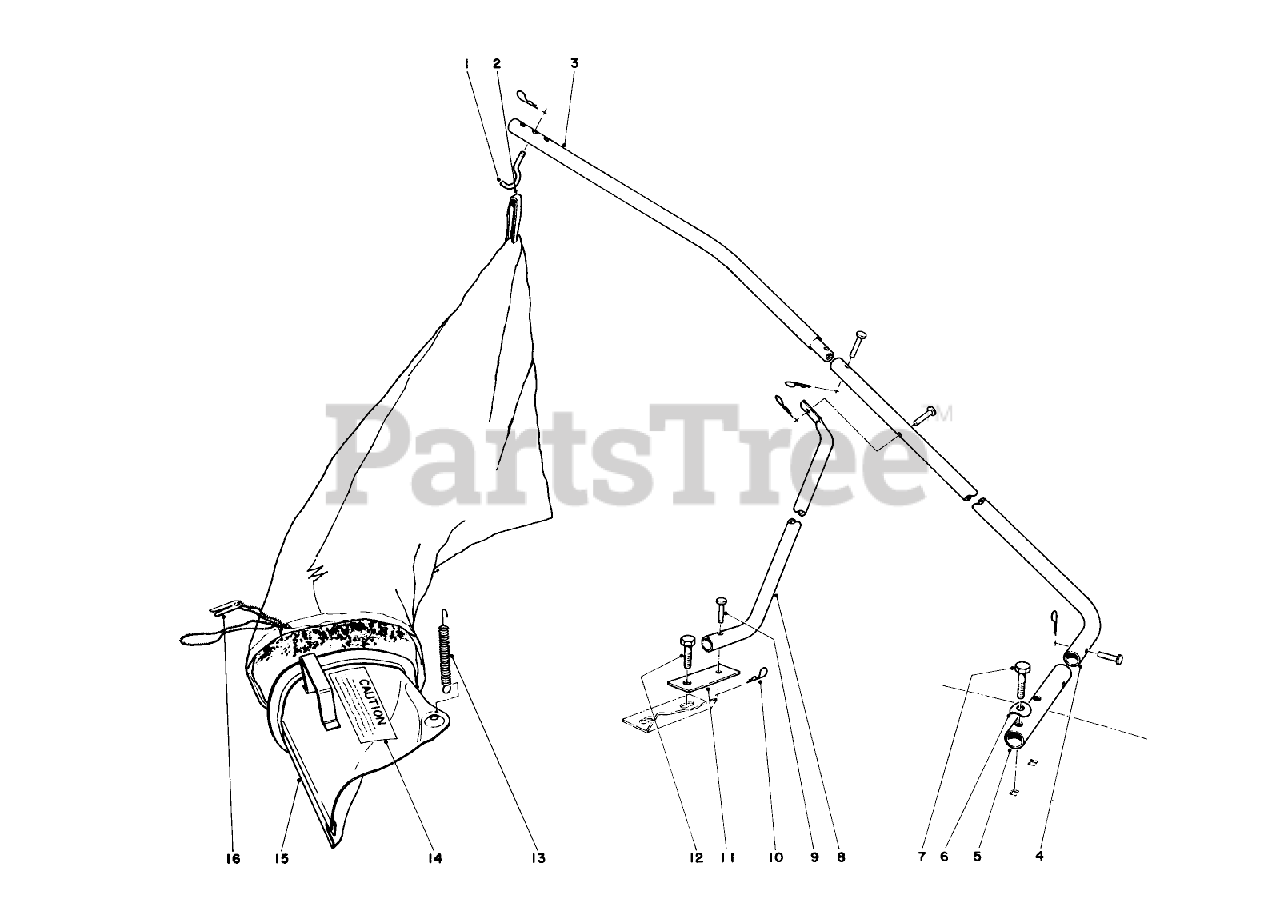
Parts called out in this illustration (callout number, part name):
2	Bag Assembly
3	Bag Arm-Rear Section
5	Socket-Bag Arm
6	Curved Washer
7	SCREW-HH
8	Brace
10	PIN-COTTER
11	Brace Support
12	SCREW-HH
13	Spring
14	Decal
15	Bag Chute (Incl. Ref. Nos. 13 & 14)
16	BAG CORD FASTENER
